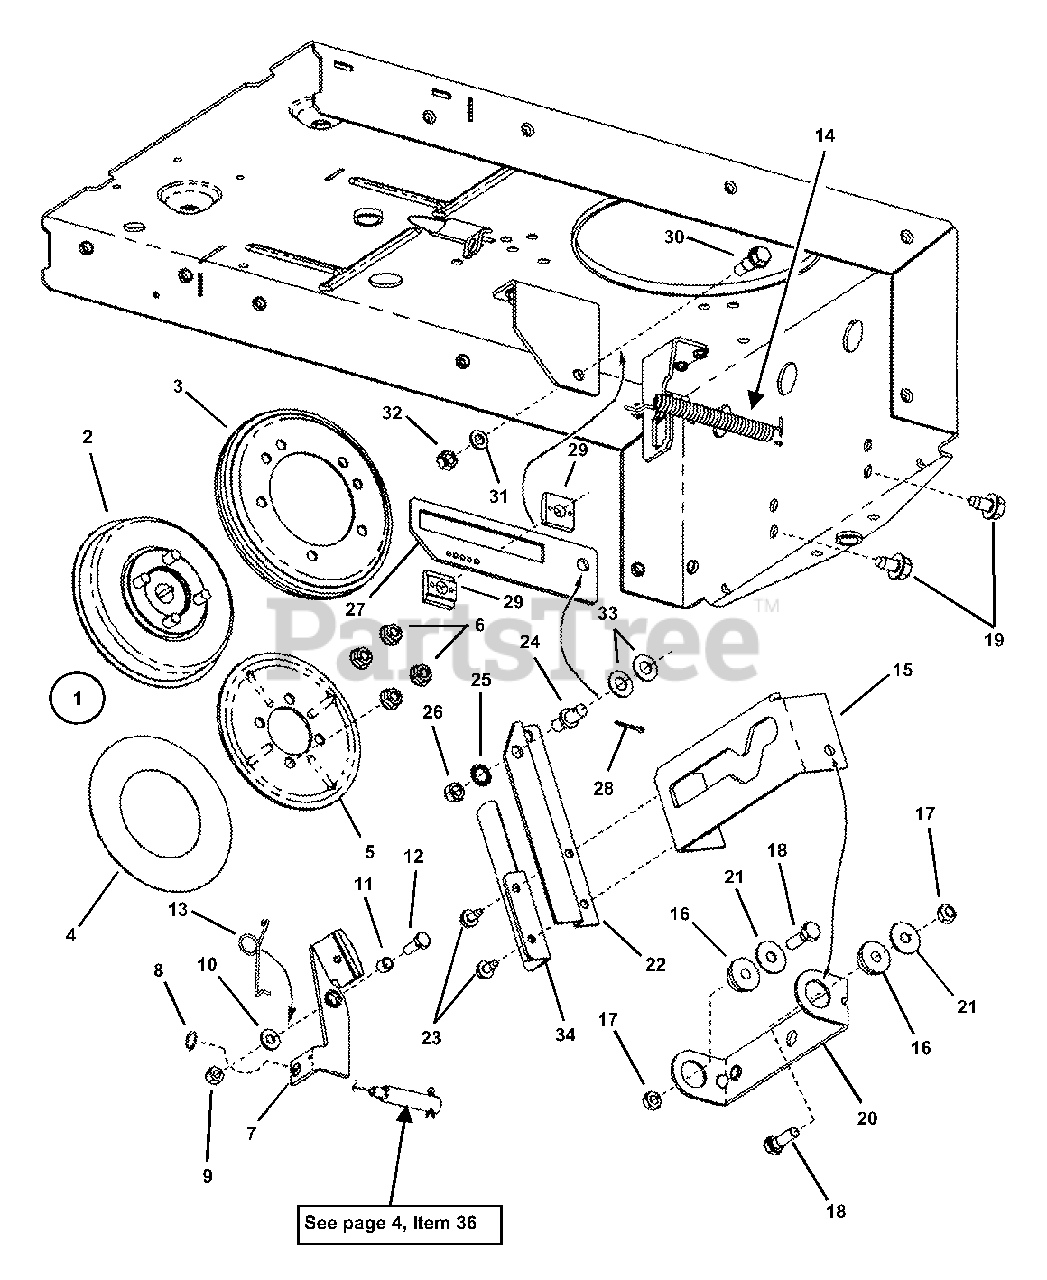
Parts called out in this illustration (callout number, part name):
1	ASSEMBLY, Smooth Clutch
2	ASSEMBLY, Driven Disc Hub
3	DISC, Driven (rubber tire bonded to rim)
4	WASHER, Thrust
5	PLATE, Drive Disc
6	NUT, 5/16-18 Hex Flange Lock
7	ASSEMBLY, Brake Lever
8	RING, 3/8" External Retaining
9	NUT, 1/4-28 Hex Top Lock
10	WASHER, 1/4" Flat
11	SPACER
12	SCREW, 1/4-28 x 1" Hex Head Cap, Grade 5 (washer face)
13	SPRING, Brake Return
14	SPRING, Clutch Brake
15	LIFT, Yoke
16	BEARING, Yoke
17	NUT, 5/16-24 Hex Center Lock
18	SCREW, 5/16-24 x 1" Hex Head Cap, Grade 5
19	SCREW, 3/8-16 x 5/8" Hex Washer Self-Tap
20	COLLAR, Yoke
21	WASHER, 5/16" Flat
22	ARM, Yoke
23	SCREW, 1/4-20 x 1/2" Hex Washer Self-Tap
24	STUD (3/8-24 thread)
25	WASHER, 3/8" Internal Tooth
26	NUT, 3/8-24 Hex, Grade 5 or B
27	BRACKET, Slide
28	PIN, 3/32 x 3/4" Cotter
29	SLIDE HALF
30	BOLT, 5/16-18 Shoulder
31	WASHER, 5/16" Split Lock
32	NUT, 5/16-18 Hex, Grade 5 or B
33	WASHER, 3/8" SAE Flat
34	ASSEMBLY, Leaf Spring
